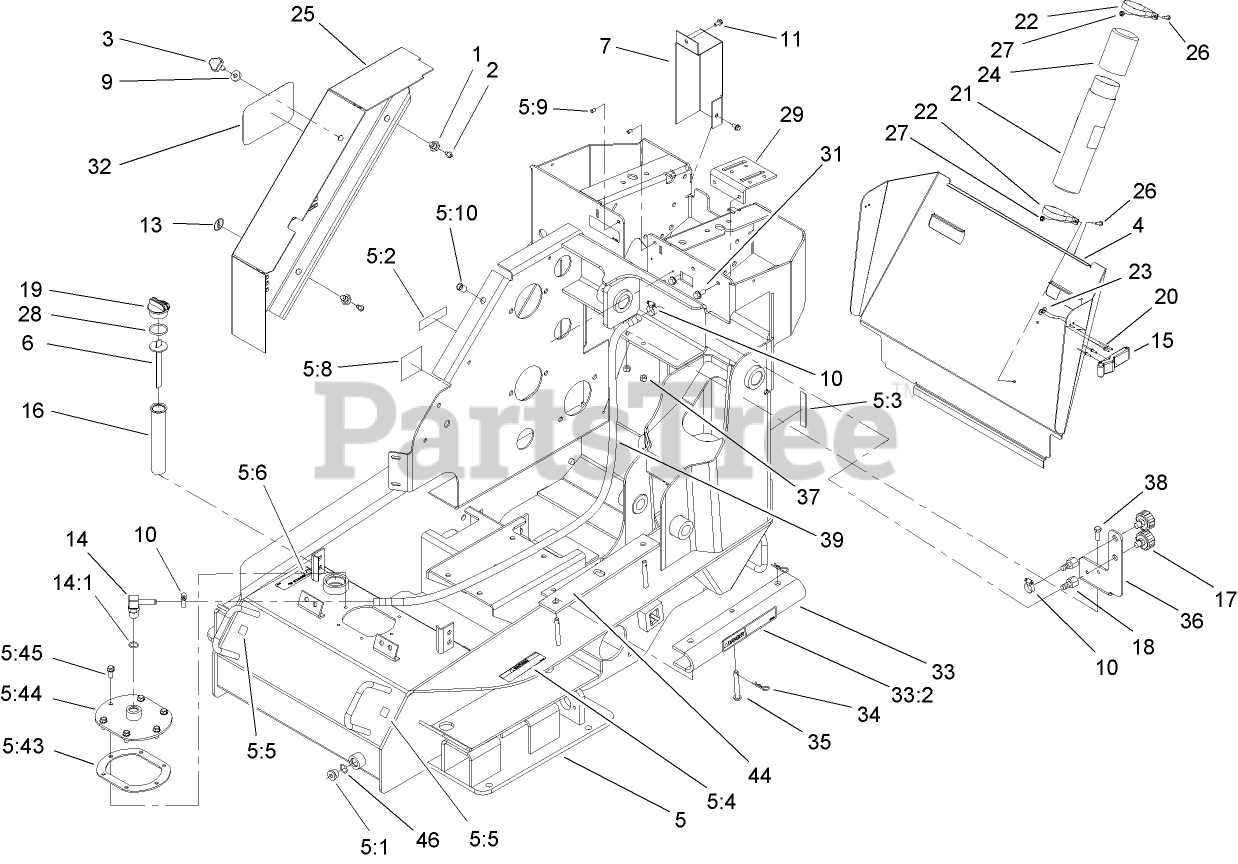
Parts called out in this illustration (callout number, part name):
1	MOUNT-SIDEPANEL
2	SCREW-PLASTITE
4	COVER-REAR
5	FRAME ASM
5:1	PLUG-HYD, HH
5:2	DECAL-COVER, MISSING
5:3	DECAL-BRAKE
5:4	DECAL-PINCH
5:5	DECAL-POINT, LIFT
5:6	DECAL-OIL, HYD
5:8	DECAL-BELT ROUTING
5:9	INSERT-NUT
5:10	INSERT-NUT
5:43	GASKET-COVER, ACCESS
5:44	COVER ASM
5:45	SCREW
6	DIPSTICK-OIL
7	COVER-PULLEY
9	WASHER-RUBBER
10	CLAMP-HOSE
11	SCREW-HWH
13	DECAL-GREASE
14	FITTING-HYD, 90 DEG
14:1	O-RING
15	LATCH
16	FILTER-SCREEN
17	BREATHER
18	FITTING-STRAIGHT
19	PLUG-PLASTIC
20	RIVET-POP
21	TUBE-MANUAL
22	CLAMP-R
23	WASHER-BACK
24	CAP-HOUSING
25	COVER-BELT
26	SCREW-PPH
27	NUT-LOCK, NI
28	O-RING
29	BRACKET-MOUNT, THROTTLE
31	SCREW-HWHTF
33	LOCKING ARM ASM
33:2	DECAL-DANGER
34	PIN-HAIR
35	PIN-CLEVIS
36	BRACKET-FILTER
37	NUT-LOCK, NI
38	SCREW-HH
39	HOSE-FUEL
44	PAD-RUBBER
46	O-RING
